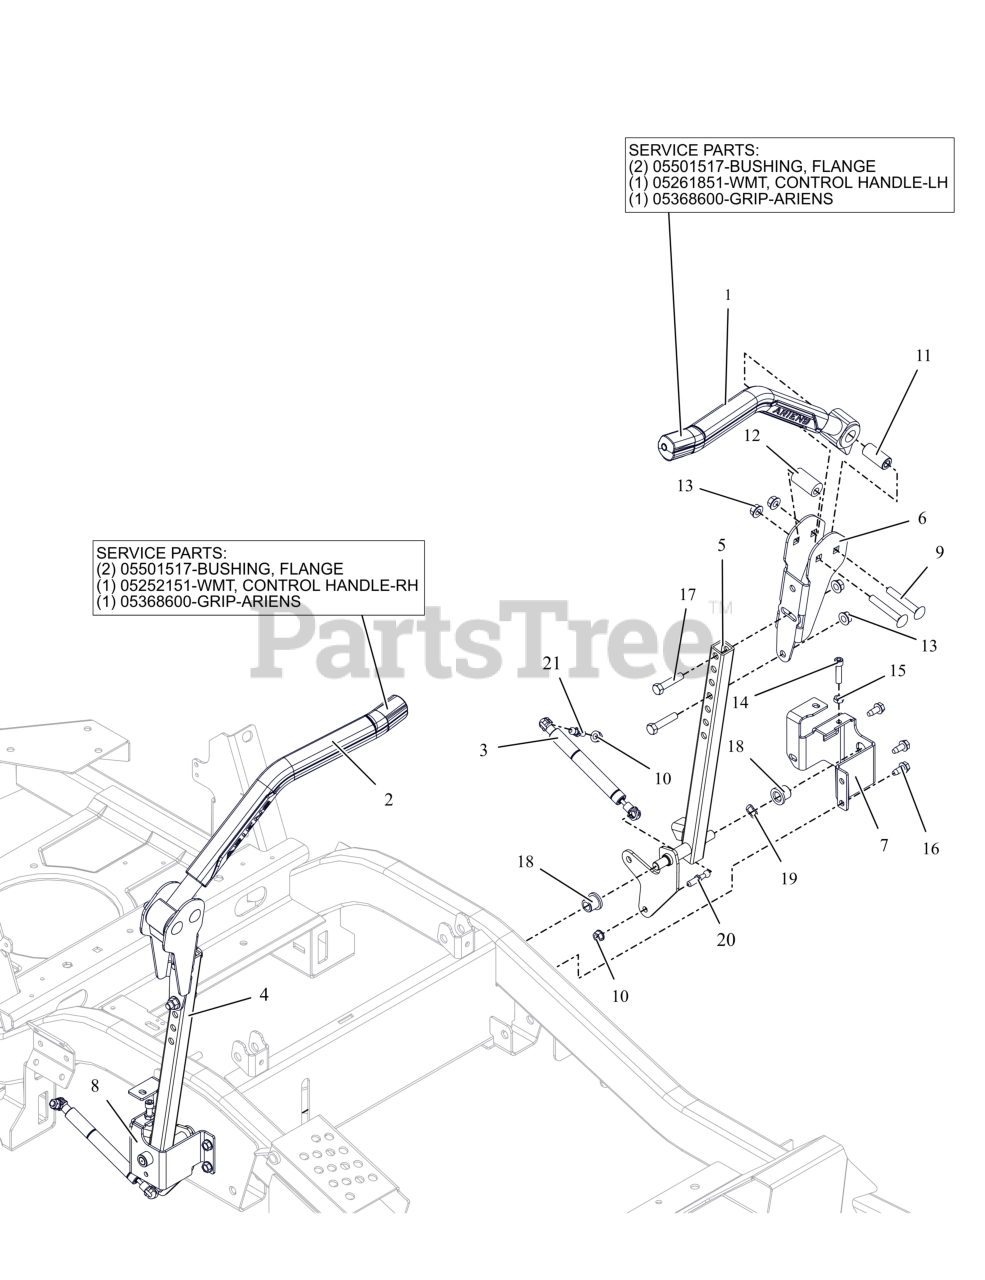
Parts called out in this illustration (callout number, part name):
1	ASM, STEERING HANDLE-LH-A
2	ASM, STEERING HANDLE-RH-A
4	WLDMT, STEERING RH
5	WLDMT, STEERING LH
6	ADJ UPPER CONTROL ARM BRKT-BLK
7	BRKT, STEERING ARM MOUNT -LH
8	BRKT, STEERING ARM MOUNT -RH
9	BLT, RHSSN.38-16X2.50 G5 ZCC
10	NUT,LK-CTR-FLG .31-18 GF ZCC
11	SPACER, STEERING ARM
12	BSHG, ECCENTRIC.406X.875X1.625
13	NUT-LK-TOP-FLG .38-16 ZC120
14	BLT, SHCS .312-18X1.25 G8 SS
15	NUT-JAM .312-18 G2 ZCC
16	SCR,TAP .312-18X.75 HWH TR ZCC
17	BLT, HEX .38-16X1.75 G5 ZCC
18	BHSG-FLG .500X.750X.750X.125
19	WAVE WASHER .531X.781X.125FH
20	STUD-BALL-THREADED
21	STUD- BALL
